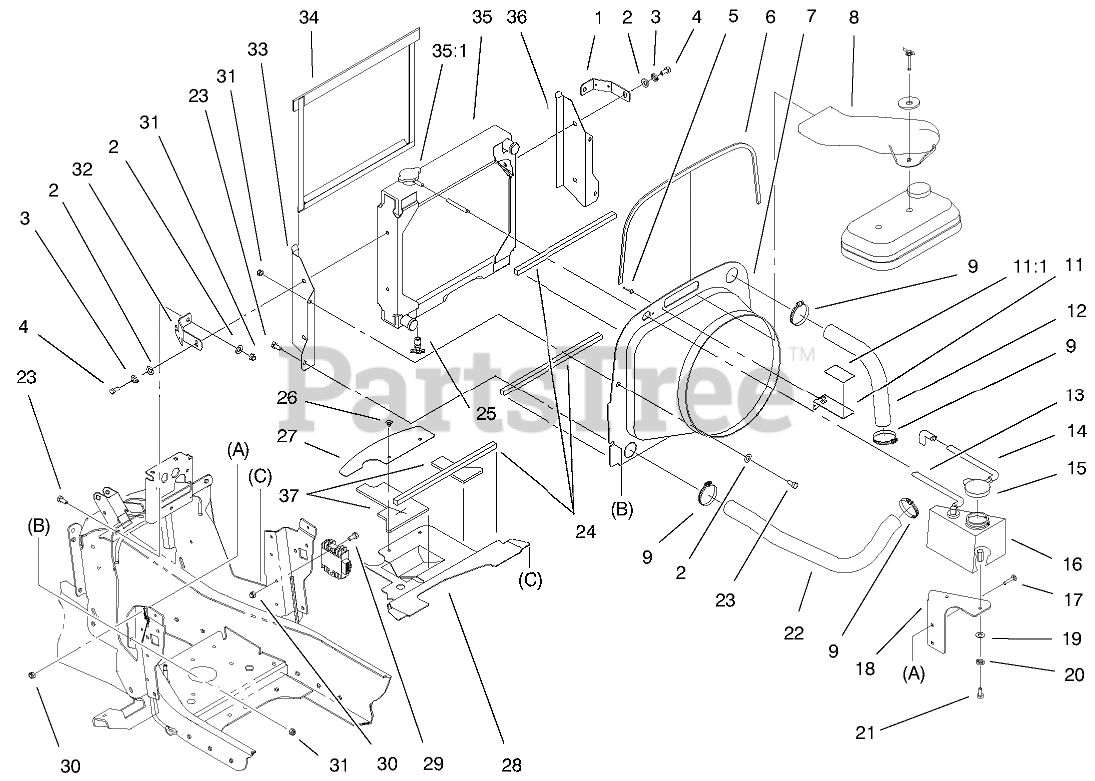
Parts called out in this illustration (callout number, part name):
1	Strap-Radiator
2	WASHER-PLAIN
3	WASHER-LOCK
4	SCREW-HH
5	RIVET-POP
6	TRIM - LOC 31"
7	SHROUD - FAN
8	DUCT - AIR, KAWASAKI
9	CLAMP-HOSE
11	FAN/DECAL ASM
11:1	DECAL - WARNING
12	HOSE - RAD. KAWASKI
13	HOSE - FUEL LINE
14	HOSE - OVERFLOW
15	CAP - COOLANT RESERVOIR
16	BOTTLE - OVERFLOW
17	BOLT-CARR
18	Brkt-Bottle
19	WASHER-FLAT
20	WASHER-LOCK
21	SCREW-HH
22	HOSE - RAD. KAWASKI
23	SCREW-HH
24	FOAM - RADIATOR/SHROUD
25	VALVE - DRAIN
26	RIVET - PLASTIC
27	BAFFLE - TOWER REAR
28	BAFFLE - TOWER
29	SCREW-HH
30	NUT-HEX
31	NUT-LOCK, NI
32	Bracket-Relay
33	Support-Radiator RH
34	SCREEN - CHAFF
35	RADIATOR - GAS
35:1	CAP-RADIATOR
36	Support-LH Radiator
37	FOAM - BAFFLE
